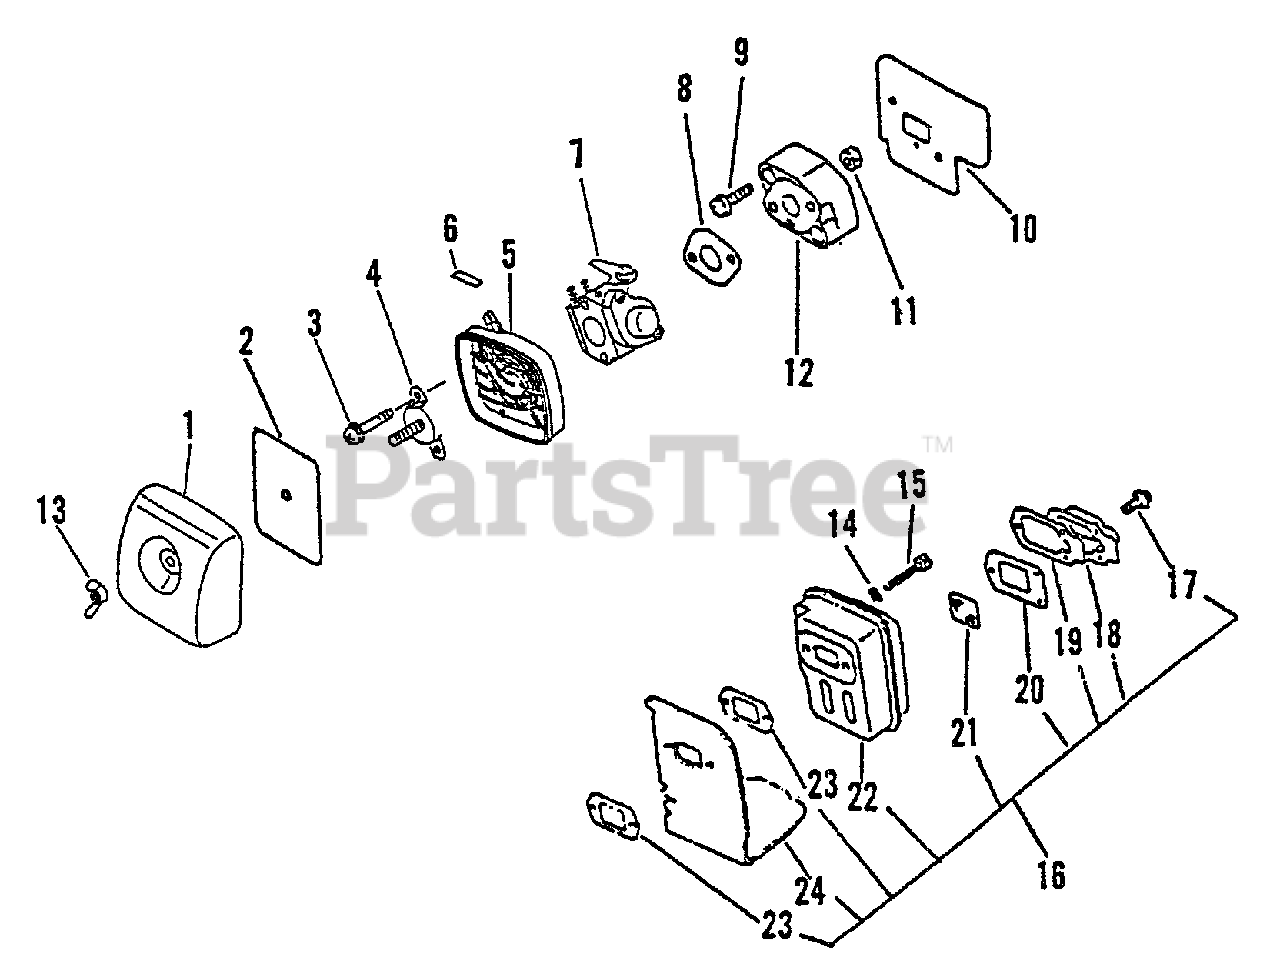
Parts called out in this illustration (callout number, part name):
1	COVER, AIR FILTER - BLACK
2	FILTER, AIR
3	SCREW 5×65
4	PLATE, PREVENT
5	CASE ASSY, AIR FILTER
6	LABEL, CHOKE
7	CARBURETOR - C1U-K26A
8	GASKET, INTAKE
9	SCREW 5×22
10	GASKET, INTAKE
11	NUT M5
12	INSULATOR, INTAKE
13	WINGNUT - 6
14	WASHER, FLAT 5.5×10×0.8
15	BOLT 5×55
16	MUFFLER ASSY
17	SCREW 4×10
18	GUIDE, EXHAUST
19	GUIDE, EXHAUST - INNER
20	GASKET, EXHAUST
21	SCREEN, SPARK ARRESTER
23	GASKET, EXHAUST
24	COVER, MUFFLER
